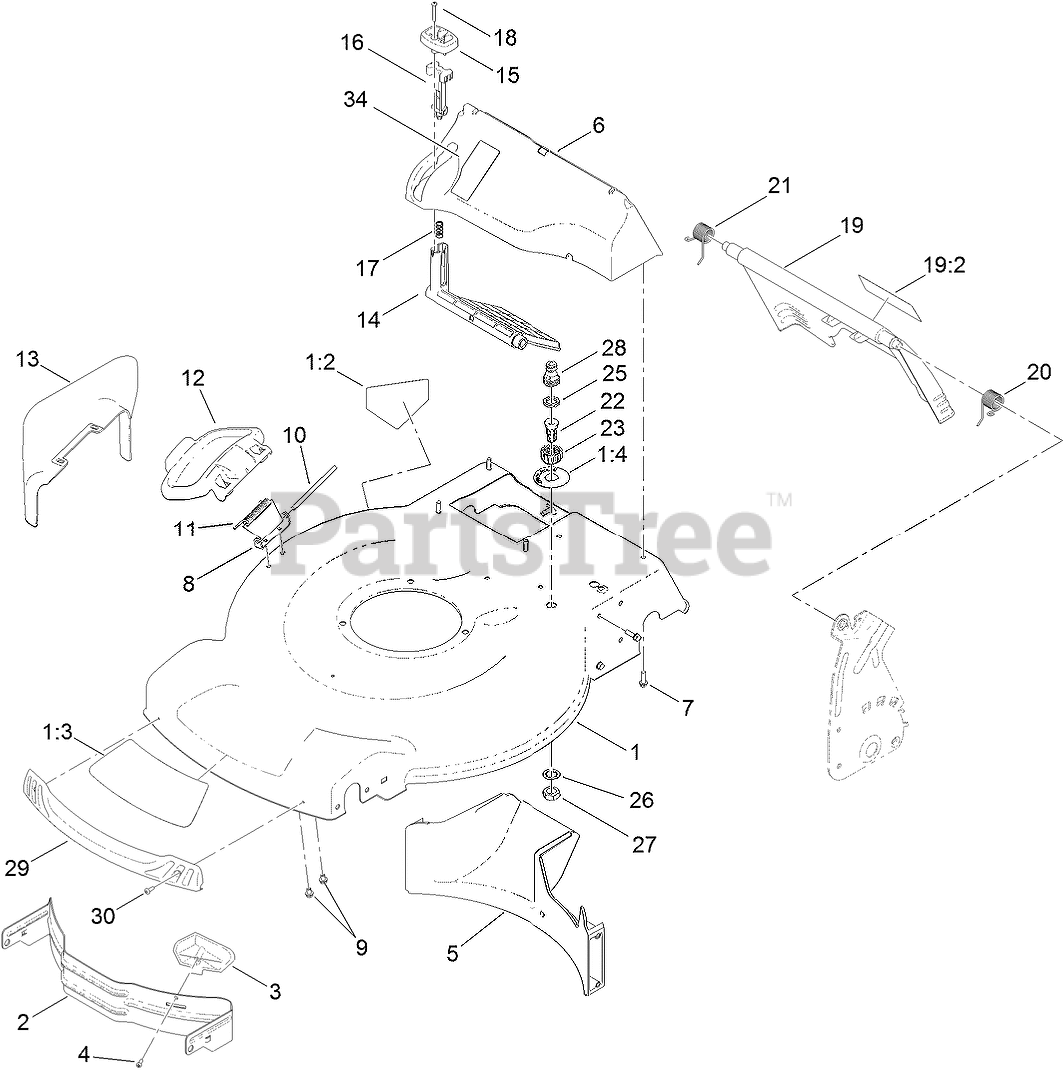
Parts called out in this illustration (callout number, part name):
1	HOUSING ASM
1:2	DECAL-DANGER
1:3	DECAL-RECYCLER
1:4	DECAL-PORT, WASHOUT
2	BAFFLE-FRONT
3	KICKER-FRONT
4	SCREW-PPH
5	BAFFLE-REAR
6	CHUTE-RECYCLE
7	SCREW-HWH
8	BRACKET-COVER
9	SCREW-HWH
10	ROD-COVER
11	SPRING-TORSION
12	DEFLECTOR-SIDE
13	CHUTE-DISCHARGE, SIDE
14	DEFLECTOR-RECYCLE
15	KNOB-RECYCLE
16	LATCH-RECYCLE
17	SPRING-COMPRESSION
18	SCREW-PPH
19	REAR DOOR ASM
19:2	DECAL-WARNING
20	SPRING-TORSION, LH
21	SPRING-TORSION, RH
22	PORT-WASHOUT
23	COUPLING-HOSE, WASHOUT PORT
25	WASHER-SEAL, WASHOUT PORT
26	WASHER-TOOTH, INTERNAL
27	NUT-JAM
28	ADAPTER-CONNECT, QUICK
29	BUMPER
30	SCREW-FORMING, THREAD
34	DECAL-BAG ON DEMAND
